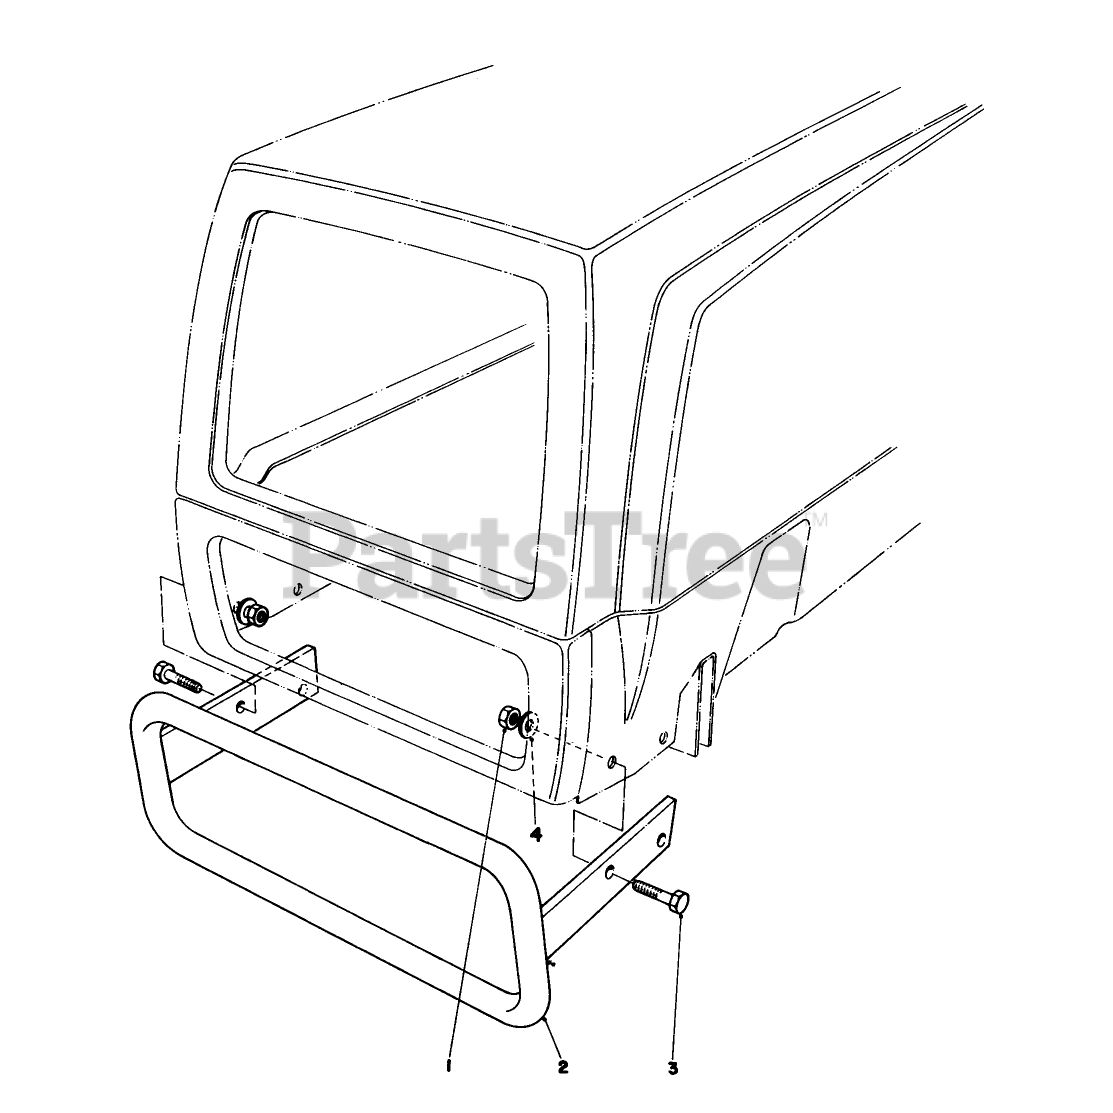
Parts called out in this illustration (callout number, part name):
1	NUT-LOCK, CONE
2	Bumper
3	SCREW-HH
4	WASHER-PLAIN
